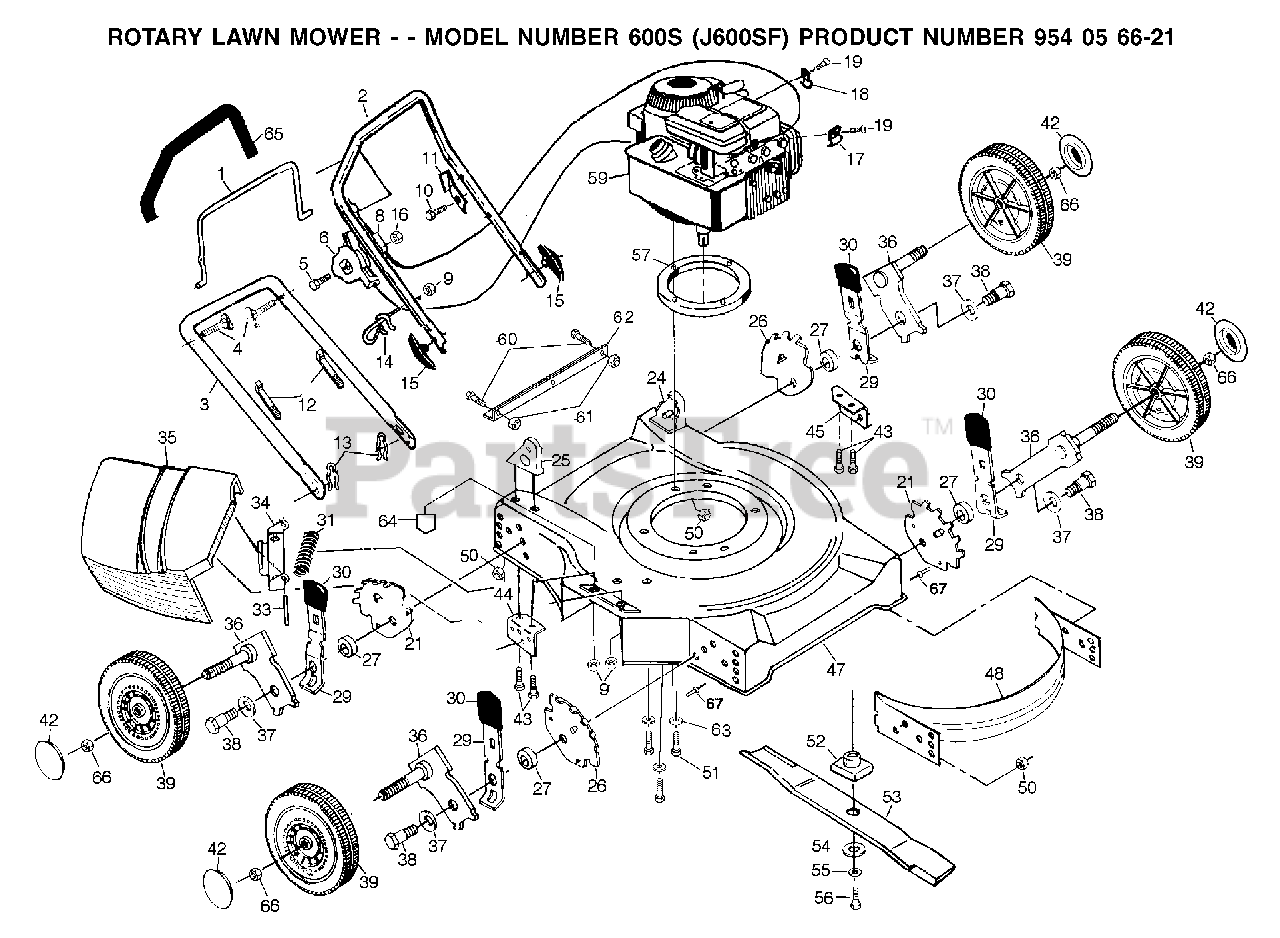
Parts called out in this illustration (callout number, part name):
1	CONTROL BAR
4	HANDLE BOLT
5	SCREW 1/4-20 X 2.12
8	ENGINE ZONE CONTROL CABLE
9	NUT
10	TAPPING SCREW
11	BRACKET UPSTOP
12	TIE GUIDE
13	HAIRPIN COTTER
14	ROPE, GUIDE
15	HANDLE KNOB
16	NUT
17	CABLE CLAMP(ENGINE)
18	GUIDE CLIP PM
19	SCREW.HEX.HEAD.WASHER.10-16
21	BRACKET.WHL.ADJ.L
24	HANDLE BRACKET ASM. LH
25	HANDLE BRACKET ASM. RH
26	BRACKET.WHL.ADJ.R
27	RP SPACER HT ADJ
29	SELECTOR SPRING
31	SPRING PM
33	ROD.HINGE.COMBI-C
34	BRACKET PM
36	AXLE, REAR
37	BELLEVILLE WASHER
38	BOLT
43	SCREW 5/16-18
44	BRKT SUPPORT(R)
45	BRKT SUPPORT(L)
50	LOCKNUT PM
52	BLADE ADAPTOR
53	%20"BLADE (FOR MODELS 50/51)
54	WASHER,HARDEN
55	LOCKWASHER
56	SCREW, HEX HD 3/8-24 X 1-3/8
64	DECAL MOWER CUT/FINGER
65	GRIP.HANDLE.FOAM
66	HEX FLANGE LOCKNT
67	RIVET BLIND
